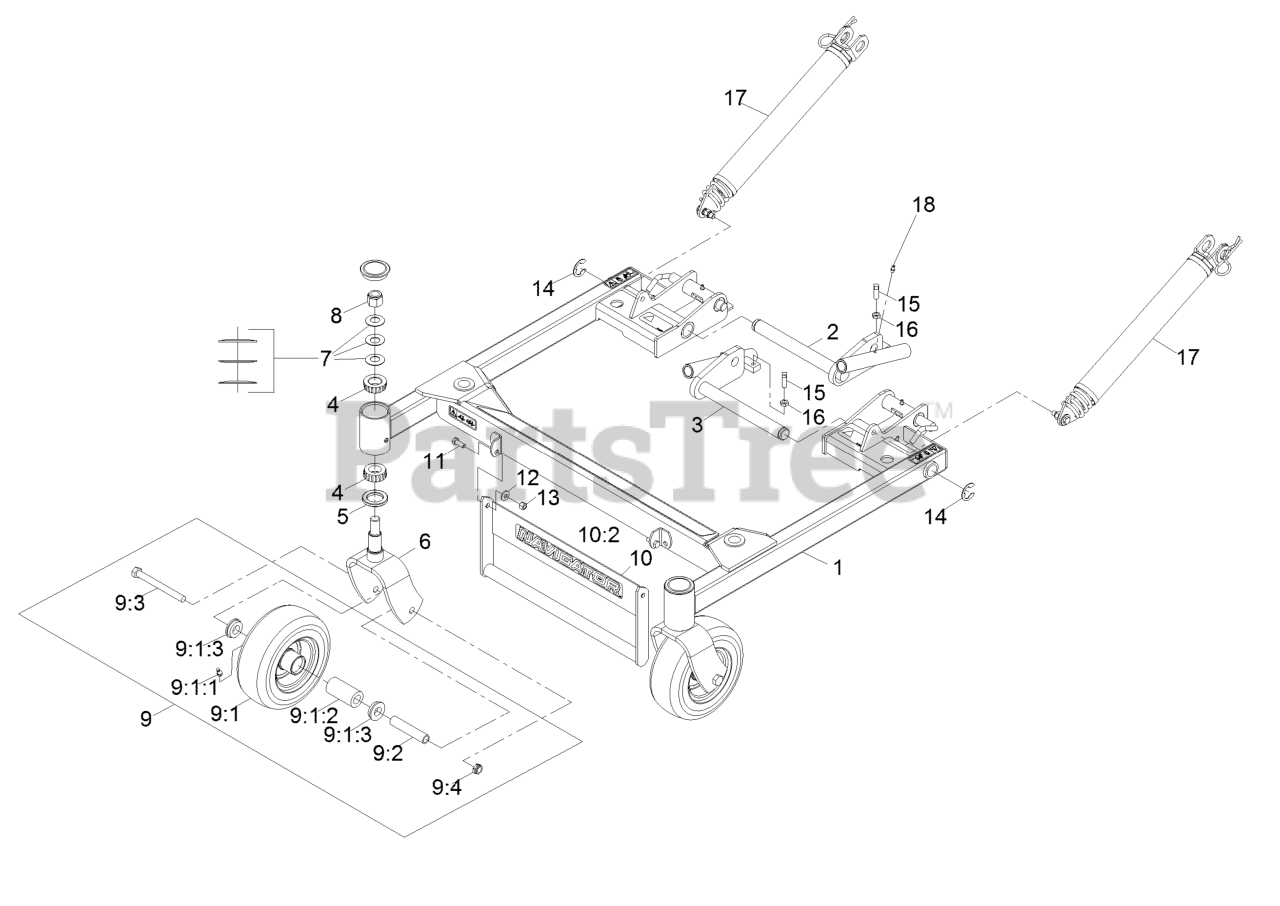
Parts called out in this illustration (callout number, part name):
1	Deck Support ASM
2	Pivot-Deck, RH
3	Pivot-Deck, LH
4	Cone-Bearing Tapered Roller
5	Seal-Grease
6	Fork-Caster
7	Washer-Spring Disc
8	Nut-Nyloc 3/4-10
9	Asm, Caster Wheel W/Axle
9:1	Asm, Wheel And Tire 8X3.00-4 Sp
9:1:1	Zerk-45deg 1/4-28
9:1:2	Bearing-Roller, Straight
9:1:3	Bushing-Flanged
9:2	Spacer-Caster, Front
9:3	Screw-HH 1/2-13 X 5
9:4	Nut-Nyloc 1/2-13 Thin
10	Asm, Deck Lift Handle W/Decal
10:2	Decal-Navigator Logo
11	Screw-HH 5/16-18 X 7/8
12	Washer-Spring Disc 5/16
13	Nut-Nyloc 5/16-18
14	Ring-Snap
15	Setscrew-SQH 3/8-16 X 1
16	Nut-Jam 3/8-16
17	Lift Assist Spring ASM
18	Zerk-1/4-28 Str
